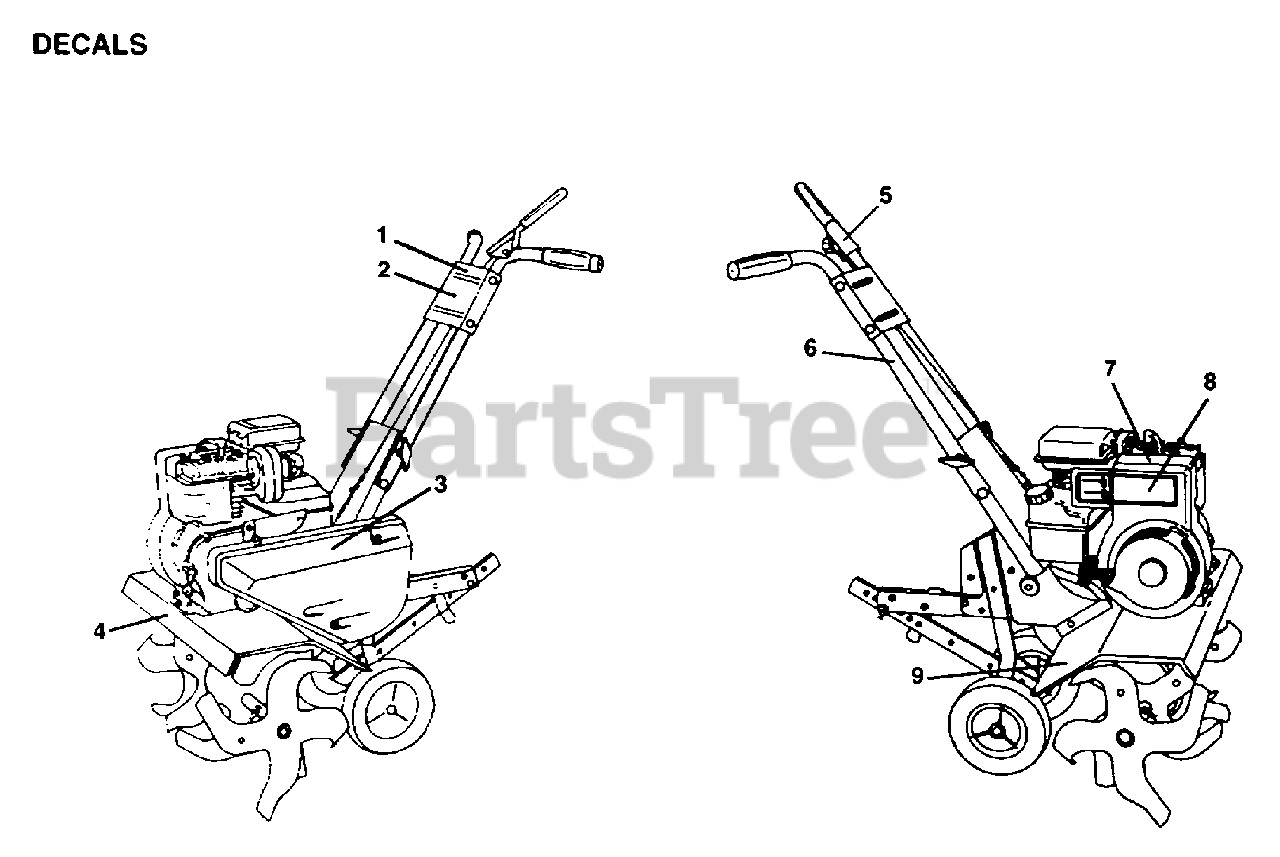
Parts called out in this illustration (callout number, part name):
1	DECAL.PNL.CNT
3	DECAL.GUARD.BELT
4	DECAL.SHIELD.TINE
5	DECAL TI
6	DECAL TI
9	DECAL TI
